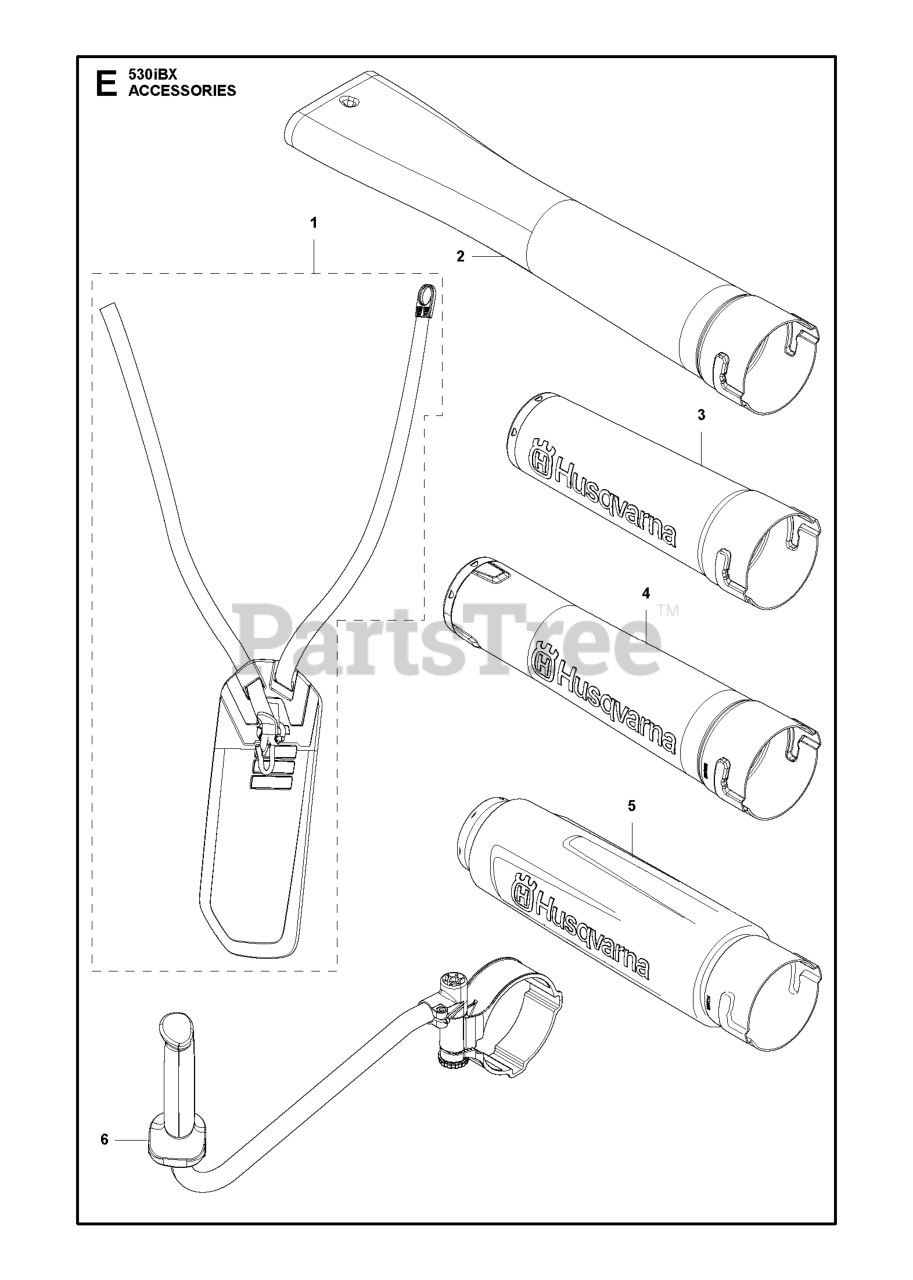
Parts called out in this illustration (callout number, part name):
1	HARNESS HIP PAD
2	BLOWER NOZZLE FOR 320IB
4	TUBE ASSY NOZZLE 536LIBX
5	TUBE ASSY NOZZLE SILENCER
